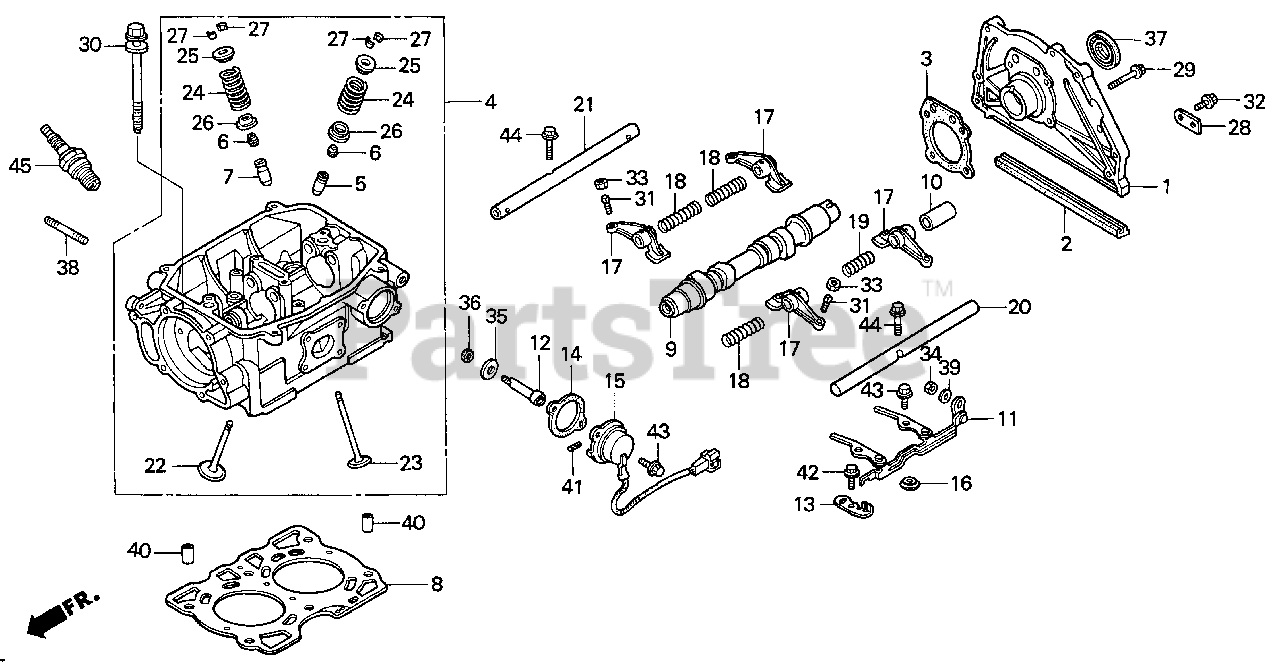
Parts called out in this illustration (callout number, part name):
1	COVER, RR. TIMING BELT
2	GASKET, RR. TIMING BELT COVER
3	GASKET, RR. TIMING BELT COVER
4	CYLINDER HEAD ASSY.
5	GUIDE, VALVE (OS)
6	SEAL, VALVE STEM (ARAI)
7	GUIDE, EX. VALVE
8	GASKET, CYLINDER HEAD
10	COLLAR, ROCKER ARM
11	DECOMPRESSION ASSY.
12	SHAFT, DECOMPRESSION
13	STOPPER, DECOMPRESSION
14	GASKET, DECOMPRESSION
15	SOLENOID, ROTARY DECOMPRESSION
16	WASHER, DECOMPRESSION
17	ARM, ROCKER
18	SPRING, ROCKER ARM A
19	SPRING, ROCKER ARM B
20	SHAFT, IN. ROCKER
21	SHAFT, EX. ROCKER
22	VALVE, IN.
23	VALVE, EX.
24	SPRING, VALVE
25	RETAINER, VALVE SPRING
26	SEAT, VALVE SPRING
27	COTTER, VALVE
28	BRACKET, WIRE HARNESS CLIP
29	WASHER, PLAIN (5MM)
30	BOLT-WASHER (10X115)
31	SCREW, TAPPET ADJ.
32	BOLT, FLANGE (6X14)
33	NUT, TAPPET ADJ.
34	NUT, HEX. (5MM)
35	WASHER (8MM)
36	OIL SEAL (8X14X5)
37	OIL SEAL (28X40X8)
38	BOLT 2, STUD (8X22)
39	BOLT, FLANGE (6X30)
40	PIN A, DOWEL (12X20)
41	PIN, SPRING (2X10)
42	BOLT, FLANGE (6X12)
43	BOLT, FLANGE (6X14)
44	BOLT, FLANGE (6X30)
45	SPARK PLUG (BPR5ES-11) (NGK)
45	SPARK PLUG (W16EPR-U11) (DENSO)
